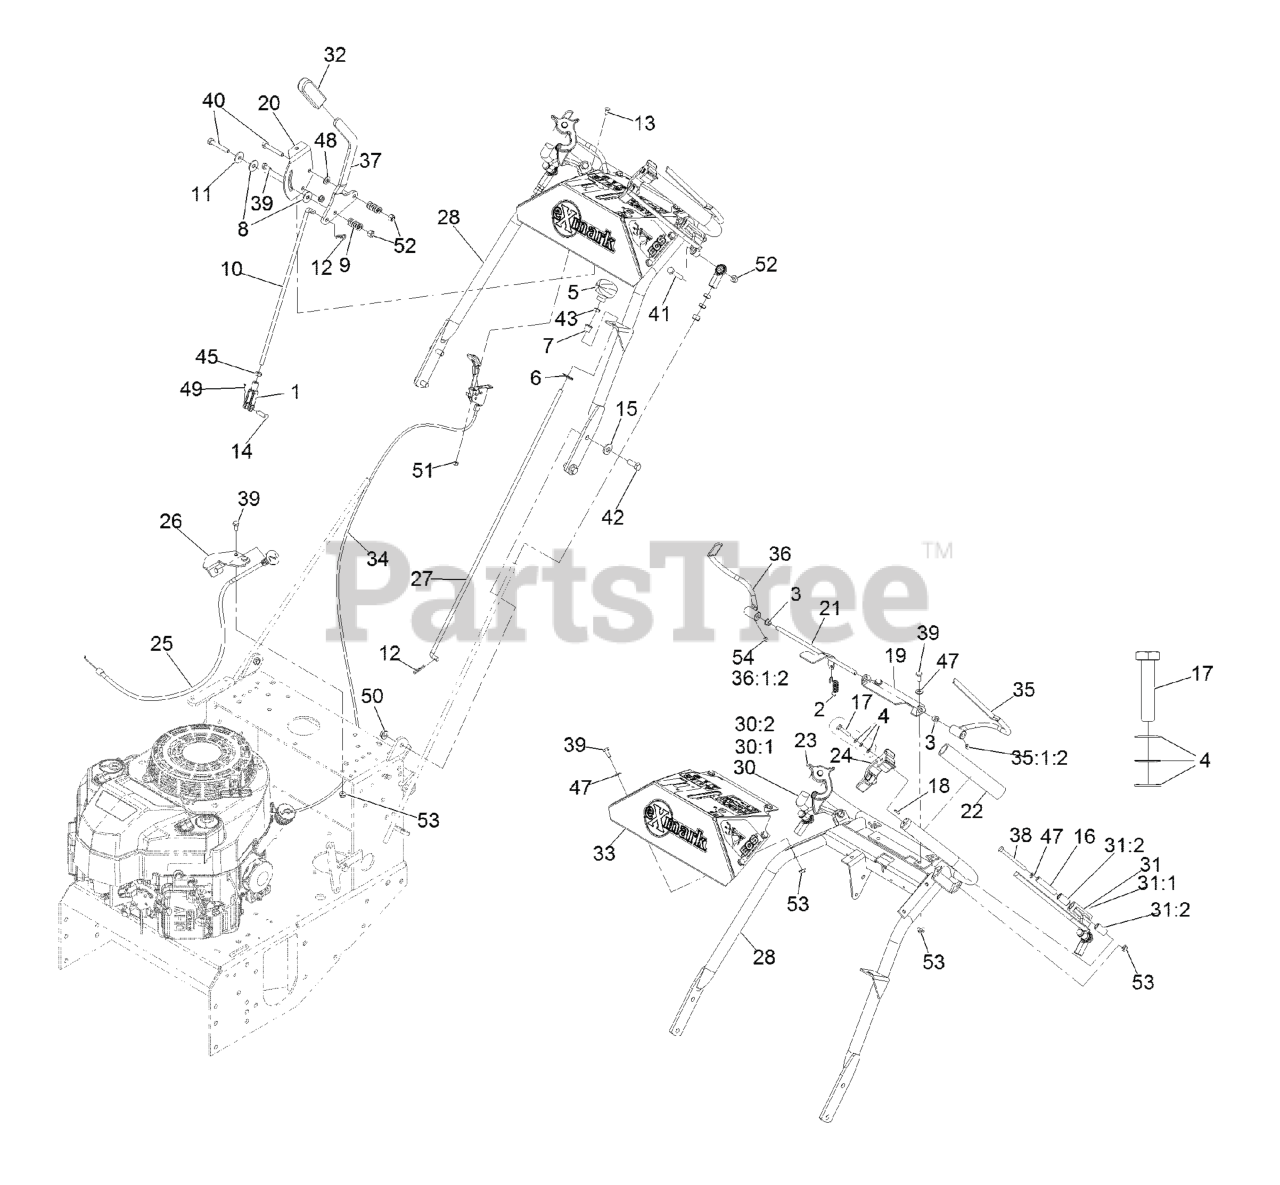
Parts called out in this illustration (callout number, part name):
1	YOKE-ADJUSTABLE
2	SPRING-EXTENSION
3	BUSHING-NYLON
4	WASHER-SPRING
5	KNOB-PUSH / PULL
6	NUT-PUSH
7	BEARING-NYLON
8	WASHER-FRICTION
9	SPRING-COMPRESSION
10	ROD-CONTROL, SPEED
11	WASHER-FRICTION
12	PIN-COTTER
13	BOLT-CARR
14	PIN-CLEVIS
15	WASHER-BELLEVILLE
16	BUSHING-LEVER, DRIVE
17	SCREW-HH
18	PIN-SPRING
19	BRACKET,OPC AXLE
20	BRACKET,SHIFTER SLIDE (PLTD)
21	WLD,OPC LEVER AXLE
22	GRIP-BAR, HANDLE
23	ASM,LATCH RH THUMB
24	ASM,LATCH LH THUMB
25	CABLE-CHOKE
26	BRACKET-CABLE, CHOKE
27	LINKAGE,BLADE PUSH/PULL
28	WLD,VH ECS HANDLE
30	DRIVE LEVER-ASM, RH
30:1	WLD,RH DRIVE LEVER
30:2	BUSHING, SLEEVE
31	DRIVE LEVER-ASM, LH
31:1	WLD,LH DRIVE LEVER
31:2	BUSHING, SLEEVE
32	GRIP-HANDLE, STEERING
33	ASM,CONSOLE W/DECALS
34	CONTROL, THROTTLE
35	WLD,LH OPC LEVER
35:1:2	SCREW-SET
36	WLD,RH OPC LEVER
36:1:2	SCREW-SET
38	SCREW-HH
39	SCREW-HH
40	SCREW-HH
41	SCREW-HH
42	SCREW-HH
43	NUT-JAM
45	NUT-JAM
47	WASHER-FLAT
48	WASHER-PLAIN
49	PIN-COTTER
50	NUT-HHF, WHIZ
51	NUT-LOCK, NI
52	NUT-LOCK, NI
54	SCREW-SET
